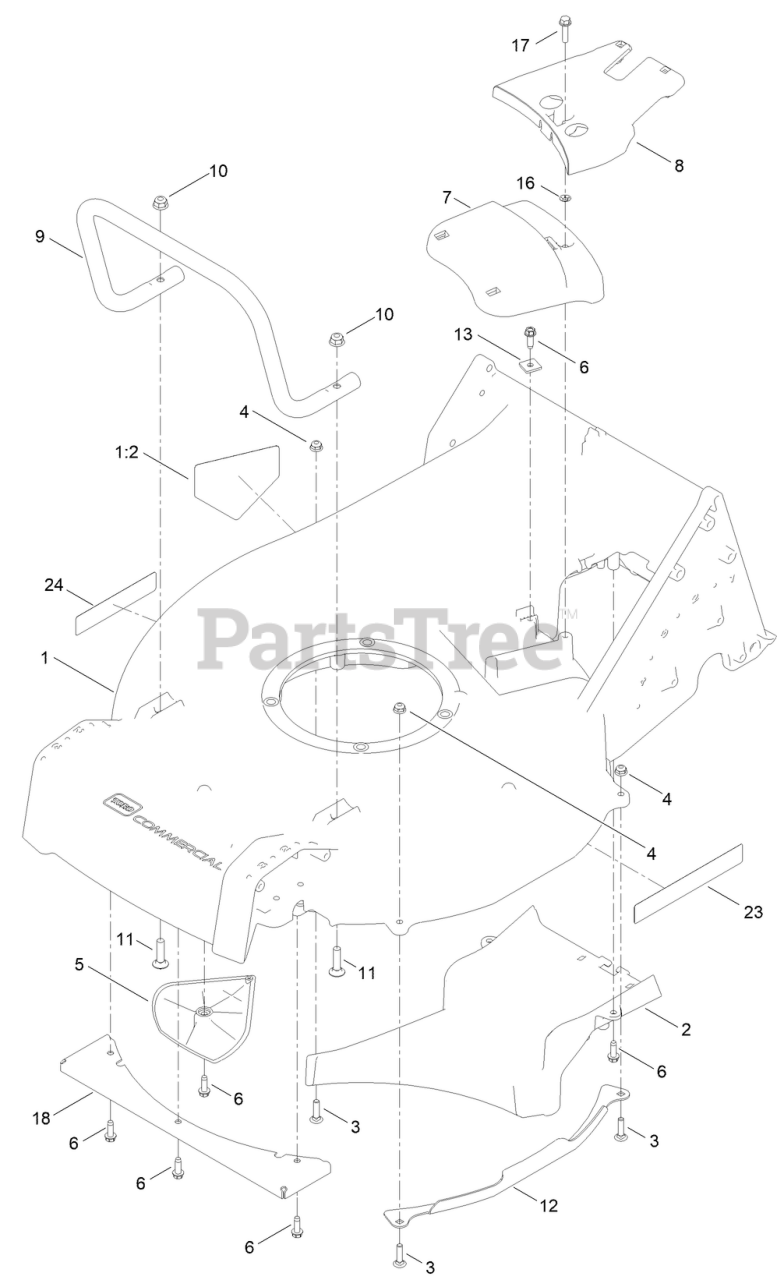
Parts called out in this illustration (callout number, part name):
1	HOUSING ASM
1:2	DECAL-DANGER
2	FLOOR-CHUTE
3	SCREW-CARR
4	NUT-HF
5	KICKER
6	SCREW-HWHTF
7	COVER-BELT, FRONT
8	COVER-BELT, REAR
9	GUARD-ENGINE
10	NUT-HF, NI
11	SCREW-CARR
12	GUARD-SIDE, DECK
13	CLAMP-CABLE
16	PUSHNUT-RETAINER, BOLT
17	SCREW-HWHTF
18	GUARD-TOE, FRONT
23	DECAL-RECYCLER
